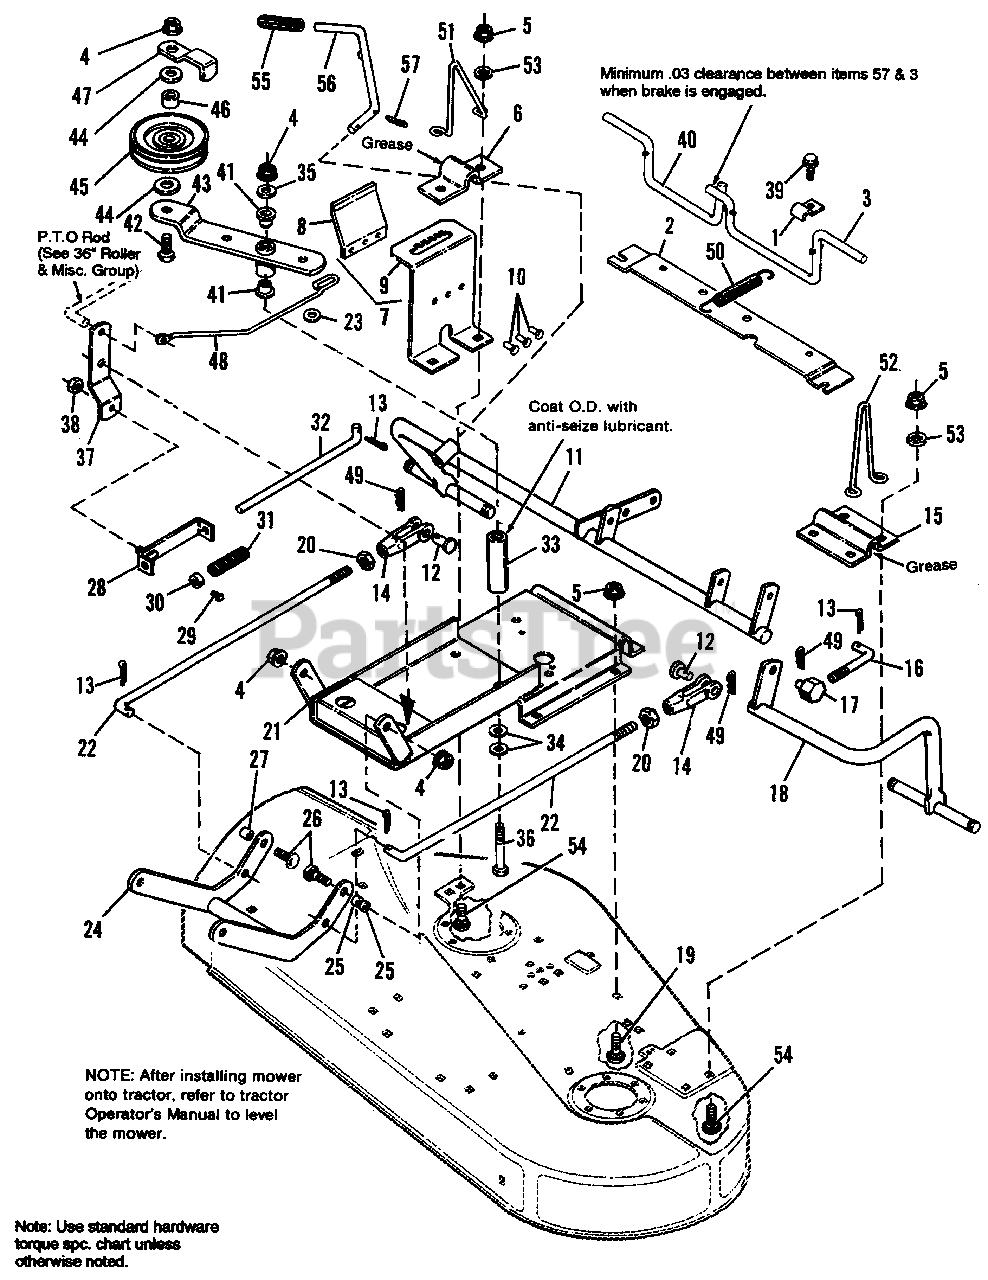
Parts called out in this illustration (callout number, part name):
1	CLIP, Brake Rod
2	SUPPORT, Brake
4	NUT, Hex Flange, 3/8-16
5	NUT, Hex, Flange, Whizlock, 5/16-18
7	QUADRANT ASSY. (Indudes Ref. Nos. 8, 9 & 10)
8	SPRING, Flat
10	Rivet, Tubular, 3/16 x 5/16
11	SUPPORT ASSY, Roller, R.H.
12	PIN, Clevis
13	PIN, Cotter, 3/32 x 3/4
14	Clevis, Adjusting
15	CLAMP, Adjusting, Wheel Support
18	SUPPORT ASSY., Roller, LH.
19	CARRIAGE BOLT, 5/16-18 x 3/4
20	NUT, Hex, Full, 3/8-16
21	SUPPORT ASSY., Mower
22	ROD, Height Adjustment
23	WASHER, 13/32
24	ARM ASSY., Rocker
26	CARRIAGE BOLT, 3/8-16 x 1-1/4
28	GUIDE ASSY., Rod
29	SETSCREW, 1/4-20 x 3/8
30	COLLAR, Set
32	ROD, Clutch
35	WASHER, Plain, 13/32
36	CAPSCREW, Hex Hd., 3/8-16 x 23/4
38	LOCKNUT, Hex, 5/16-18
39	SCREW, Hex Hd., Taptite 5/16-18 x 1/2
41	BUSHING, Universal
42	CAPSCREW, Hex Hd., 3/8-16 x 1-3/4
43	LEVER ASSY., Clutch (Incl. Ref. No. 56 Qty. 2)
44	WASHER, Plain
45	PULLEY ASSY.
47	GUARD, Spring
49	CUP, Hair Pin
51	UP-STOP, R.H.
52	UP-STOP, L.H.
53	WASHER, Plain
54	CARRIAGE BOLT, 5/16-18 x 1-1/4
55	GRIP, Handle
56	LEVER, Control
57	COTTER PIN
